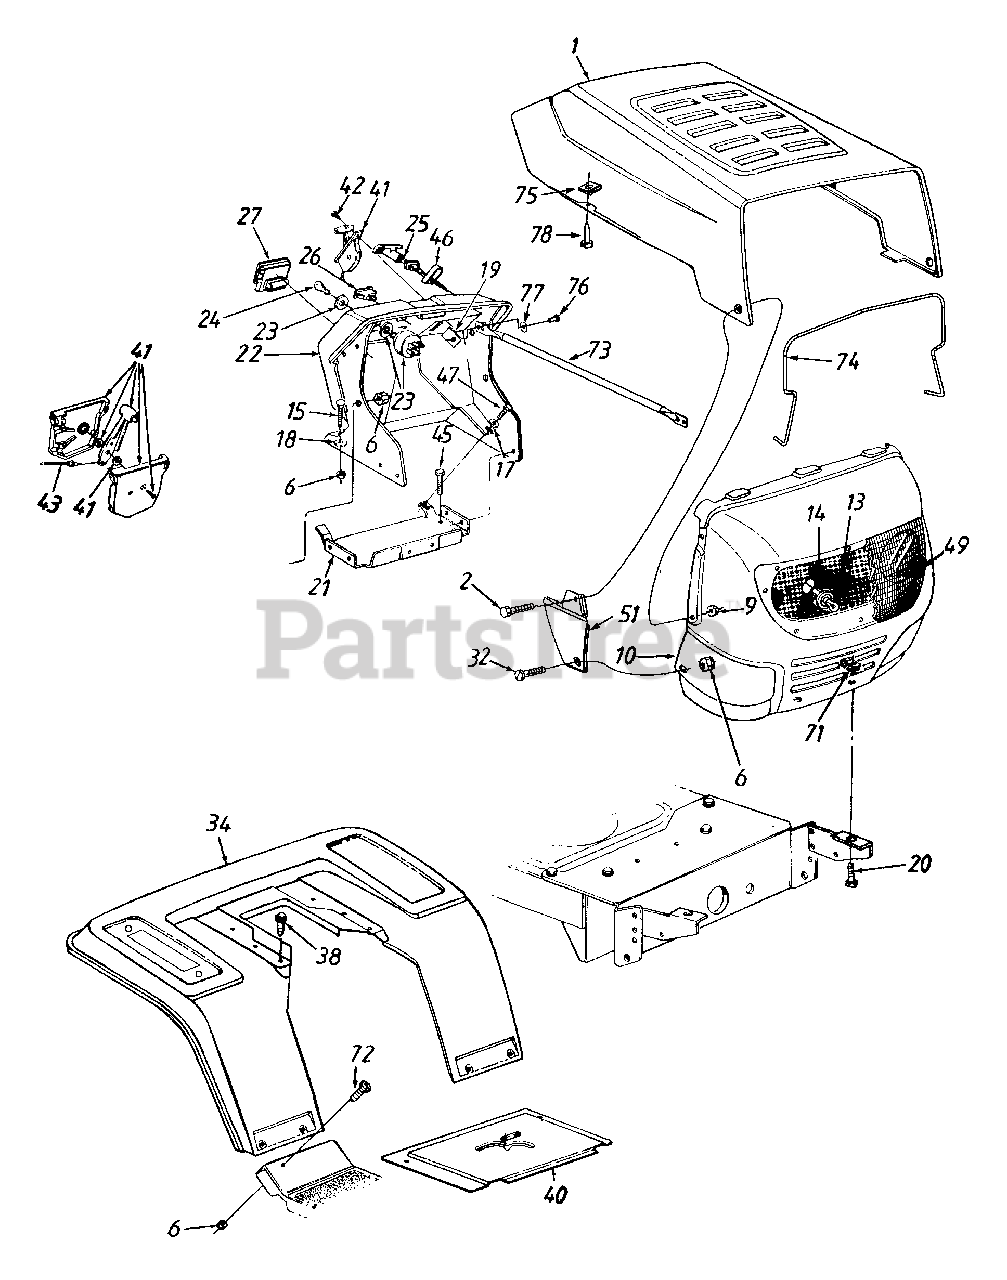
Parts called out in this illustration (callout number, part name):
6	Hex Sems Nut 1/4-20 Thd.
9	Flange L-Nut 1/4-20 Thd.
13	Lamp
14	Socket
15	Carriage Bolt 1/4-20 x .75" Lg.
17	Fl-Wash. .281" I.D. x .73" O.D.
18	Bolt Retainer 1/4" I.D.
19	Speed Nut 1/4-20 Thd.
20	Hex Bolt 5/16-18 x .1" Lg. (Gr.5)
23	Ignition Switch
24	Ignition Key
25	Choke Control 23" Lg.
26	Light Switch
27	Ammeter
32	Pan Hd. Scr. 1/4-20 x .75" Lg.
41	Throttle Box Ass'y.
42	Truss Mach. AB-Tap Scr. #10 x .5"
43	Throttle Control Wire 18.5" Lg.
45	Hex Wash. Hd. B-Tap Scr.
46	Choke Retainer
47	Hex TT-Tap Scr. 1/4-20 x .75" Lg.
49	Lens
72	Truss Mach. Scr. 1/4-20 x .5" Lg.
75	Speed Nut
76	Hex Bolt 1/4-20 x 5/8" Lg.
77	Fl-Wash. .283" I.D. x .75" O.D.
78	Hex Hd. Tap Scr. #10-16 x .75"
